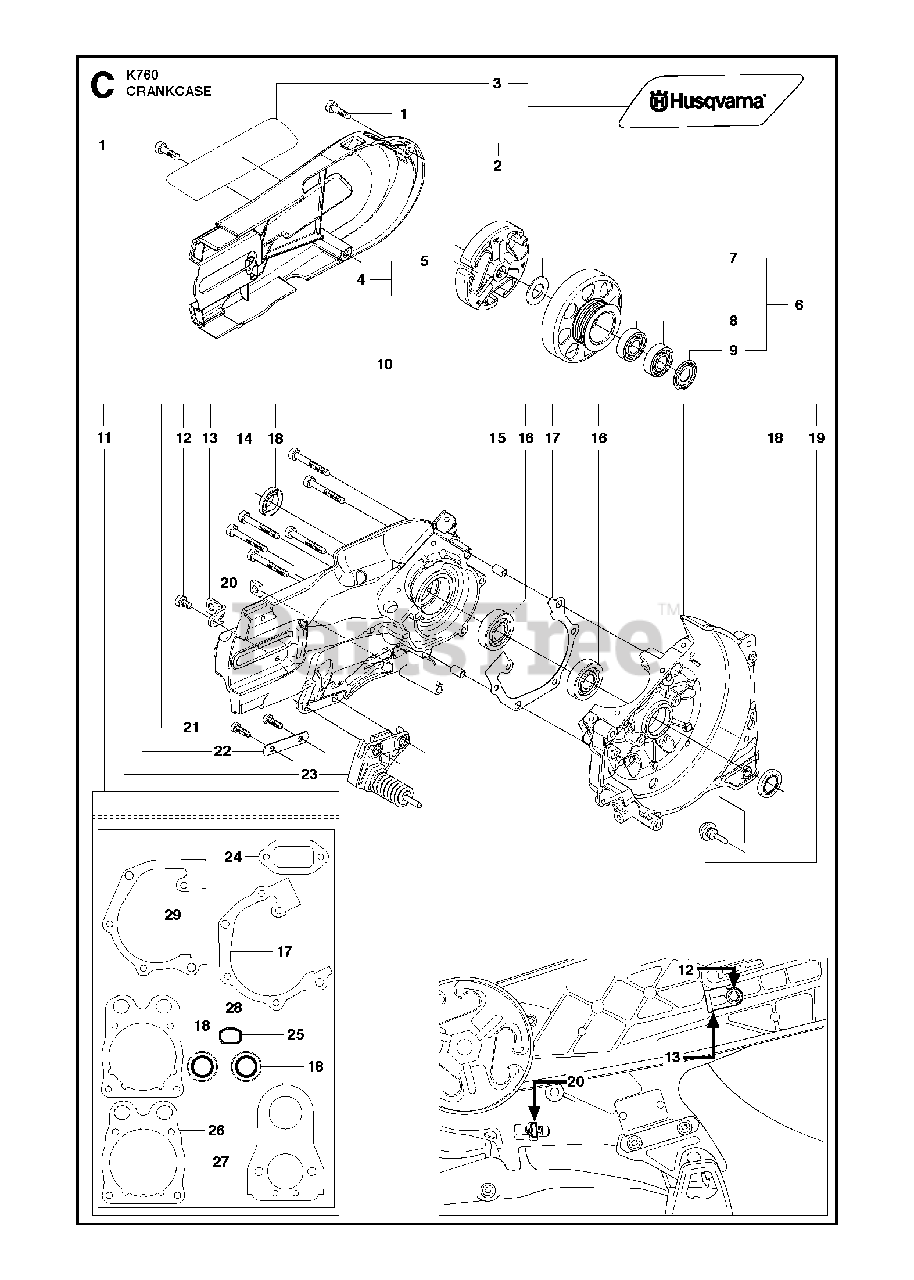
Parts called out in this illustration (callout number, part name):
1	SCREW ITXSCM
2	BELT GUARDIncl. 3
4	CLUTCH ASSYIncl. 5
5	CLUTCH SPRING
6	DRIVING PULLEY ASSYIncl. 7 - 9
7	WASHER
8	BALL BEARING
10	CRANKCASE ASSYIncl. 11-19, 21-23
11	GASKET KITIncl. 17, 18, 24-29
12	SCREW ITXSCM
14	SCREW ITXSCM
15	GUIDE BUSHING
16	BALL BEARING
17	GASKETSix hole
18	SEALING RINGBlue
21	SCREW ITXSCM
23	SPRING RETAINER12"
24	GASKET
29	GASKETFive hole
